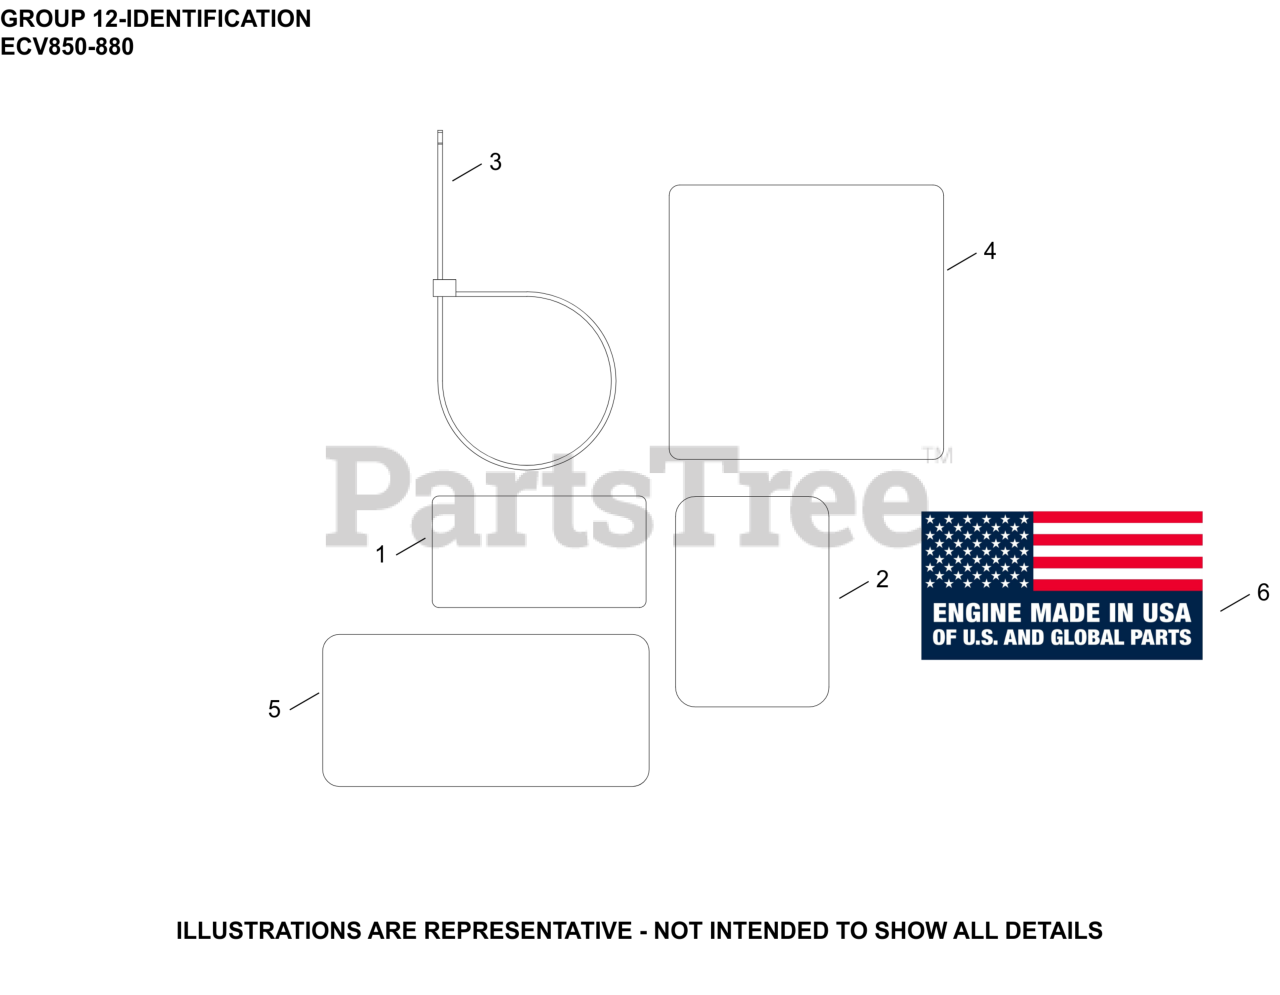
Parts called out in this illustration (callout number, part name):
1	LABEL, EFI FUEL FILTER
2	LABEL, CLEAR LAMINATION
4	DECAL, COMMAND PRO 33HP (ECV880, HDAC)
6	DECAL, USA
